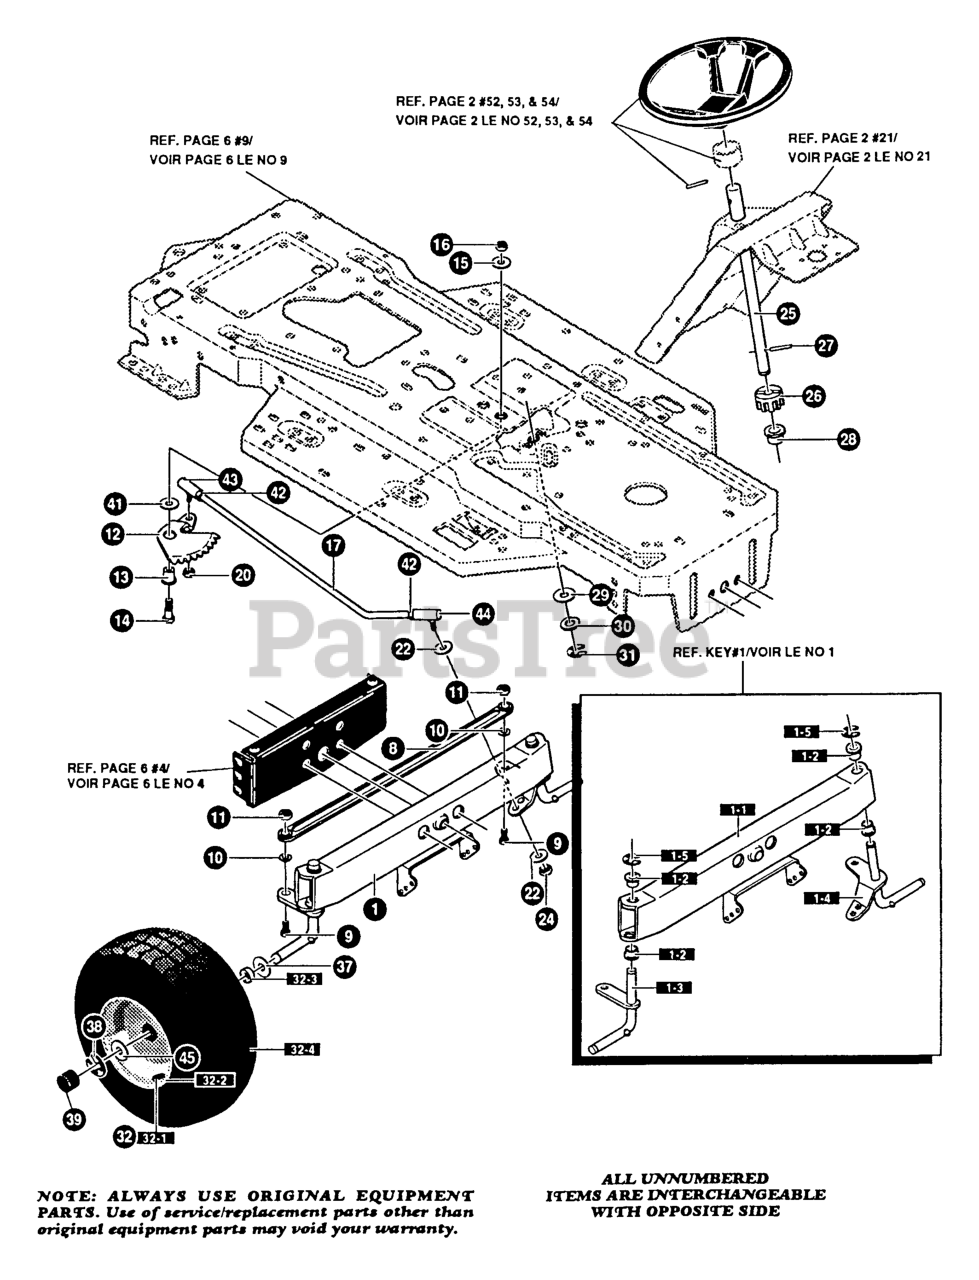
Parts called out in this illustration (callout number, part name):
1	AXLE, FRONT ASSY
1-1	FRONT AXLE
1-2	SPINDLE BEARING
1-3	SPINDLE ASSY, RH
1-4	SPINDLE ASSY, LH
1-5	RING,RETEX
8	TIE ROD ASSY
10	WASHER
11	NUT
12	SECTOR, STEERING
13	BEARING
17	STEERING LINK
22	WASHER
25	SHAFT, STEERING
26	PINION, STEER
27	PIN, DOWEL
28	BEARING
30	WASHER
31	RING, RETEX
32	TIRE 9 RIM
32-1	VALVE STEM
32-2	RIM, WHEEL
32-3	BEARING
37	WASHER
38	RING, RETEX
39	HUB CAP
41	WASHER
43	BALL JOINT
44	BALL JOINT
